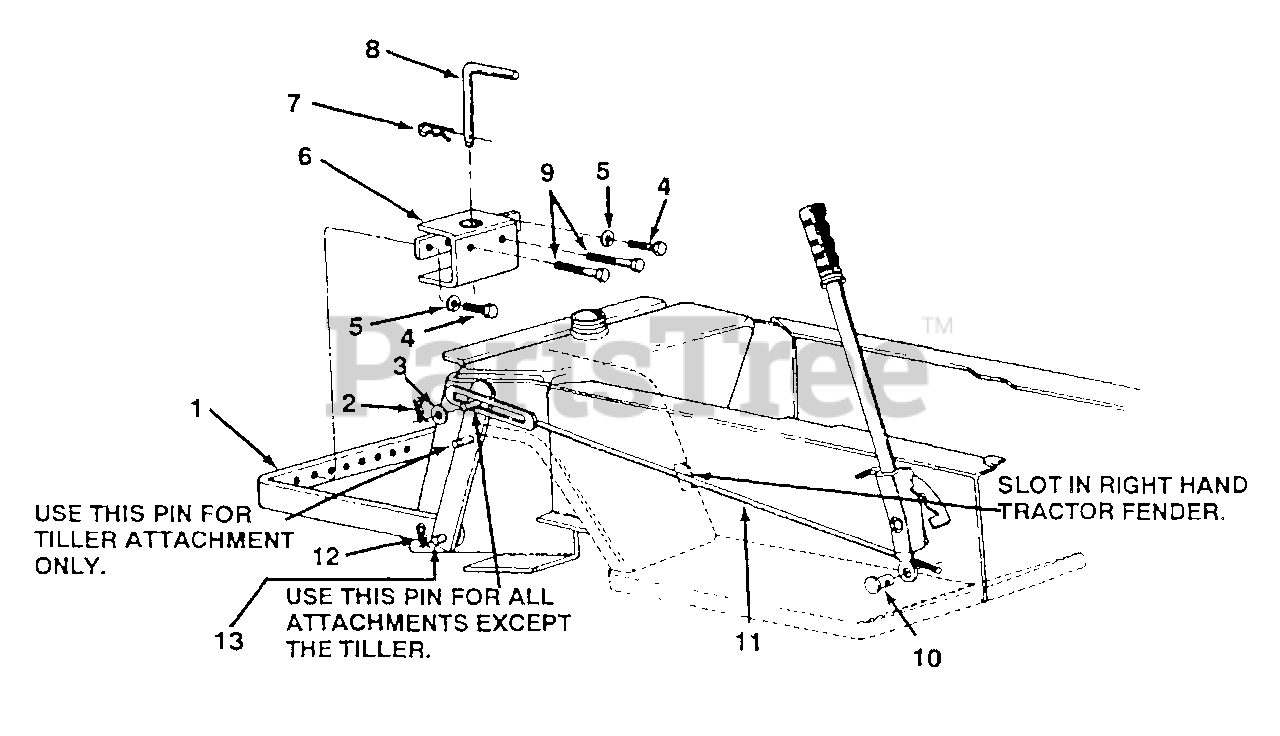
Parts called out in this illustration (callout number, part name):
3	Fl-Wash. 1/2" I.D.
4	Hex Bolt 1/2-13 x 1.0" Lg.
5	L-Wash. 1/2" I.D.
8	Hitch Pin
9	Hex Bolt 1/2-13 x 3.0" Lg.
10	Adjustment Ferrule
13	Hitch Rod
